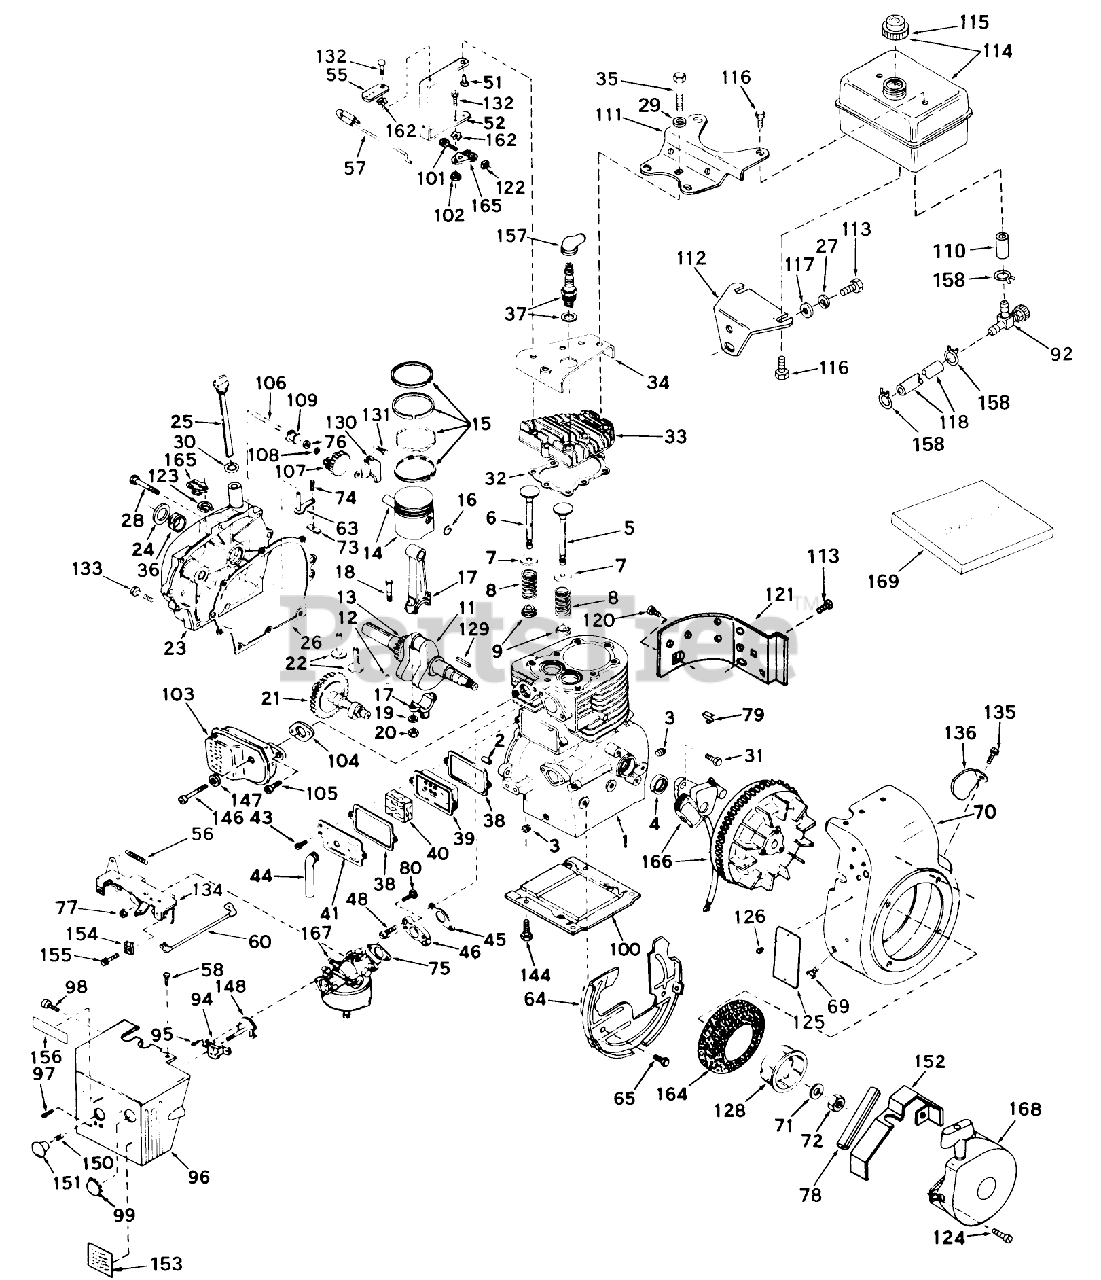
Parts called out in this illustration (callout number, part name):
1	Cylinder Assy. (Incl. Nos. 2, 3 4)
2	Pin-Dowel
3	Plug-Drain, Oil (SQH 1/4-18)
4	Seal, Oil
5	Valve, Intake (Std.)(Incl. No. 9)
5	Valve, Intake (1 /32" oversize)(Incl. No. 9)
6	Valve, Exhaust (Standard)(Incl. No. 9)
6	Valve, Exhaust (1/32" oversize)(Incl. No. 9)
7	Cap-Spring, Valve
8	Spring-Valve
9	Keeper-Spring, Valve
11	Crankshaft Assy. (Incl. Nos. 12 13)
12	Pin, Groove
13	Gear-Crankshaft
14	Piston Pin Assy. (Standard)(Incl. 2 of No. 16)
14	Piston Pin Assy. (.010 oversize)(Incl. 2 of No. 16)
14	Piston Pin Assy. (.020 oversize)(Incl. 2 of No. 16)
15	Ring Set, Piston (Std.)
15	Ring Set, Piston (.010 Oversize)
15	Ring Set, Piston (.020 oversize)
17	Rod Assy., Connecting (Incl. Nos. 18, 19 20)
18	Bolt, Connecting Rod
19	Washer
21	Camshaft, BCR
22	Lifter Valve
23	Cover, Cylinder (Incl. Nos. 24 106)
24	Oil Seal
25	Dipstick, Oil (Incl. No. 30)
26	Gasket-Cover, Cylinder
27	Lockwasher
28	Screw (1/4-20 x 1-1/4)
29	Washer
30	Gasket
31	Screw
32	Gasket-Head, Cylinder
33	CYLINDER HEAD
34	Cover, Cylinder head
35	Screw Hex Hd. Cap
36	Bushing-Crankshaft
37	SPARK PLUG
38	Gasket-Breather
39	Body-Breather
40	Element-Breather
41	Cover-Valve
43	Screw
44	Tube-Breather
45	Gasket-Intake
46	Flange, Carburetor (Incl. Nos. 77 80)
48	Screw
51	Rivet, Split
52	Lever, Governor
56	Spring, Extension
57	Link, Governor to Throttle
58	Screw-Hex Washer Hd.
60	Wire, Ground
63	ROD ASSY, Governor
64	Baffle Blower Housing
65	Screw (1/4-20x19/32)
69	Screw, Hex Hd.
70	Housing, Blower
71	Washer
73	Yoke-Governor
74	Screw (6-40x5/16)
75	Gasket-Carburetor
76	Washer-Flat
77	Nut and Lock Washer (1/4-28)
78	Seal, Snowguard
79	51004 GIL ROTARY TI
80	Screw
92	Valve-Shut Off
94	Bracket-Choke
95	Screw (10-32 x 1/2)
96	Cover, Carburetor
97	Screw (8-32 X 5/16)
98	Screw, Pan Hd. Metal
99	Plug
100	Base Engine
101	Screw
102	Nut-Lock
103	Muffler
104	Gasket Exhaust
105	Screw
106	Shaft-Governor
107	Governor Gear ASM
108	Ring-Retaining
109	Spool-Governor
110	Line-Fuel (8.62)
111	Bracket, Fuel Tank-Upper
112	Bracket, Fuel Tank-Lower
113	Screw (1/4-20x19/32)
114	53023/VAR.10/16HP O
115	Cap, Fuel
116	Screw (1/4-15x7/8)
117	Washer
118	Line-Fuel
120	Screw
121	Emnsion, Blower Housing
122	Nut-Lock
123	Ring-Retaining
124	Screw
125	IDENTIFICATION PLATE
126	DRIVE STUD
128	Cup-Starter
129	Key, Flywheel
130	Bracket, Governor
131	Screw (10-32 x 35/64)
132	Screw
133	Screw
134	Bracket Assy., Speed Control (Incl. No. 56)
135	Screw, Pan Hd. Metal
136	Screw
144	Screw
146	Screw Hex Hd. Cap
147	Washer
148	Plate, Choke
150	Spring, Compression
151	Knob, Choke
152	Guard, Starter
153	Decal, Operating
154	Conduit
155	Screw (10-32 x 3/8)
156	Decal, Choke
157	Cover-Spark Plug
158	Clamp-Line, Fuel
162	Washer-Lock
164	Screen, Air
165	Clamp-Lever, Governor
166	Magneto
167	Carburetor
168	Starter Assy., Rewind
169	Gasket Set (Incl. Items Marked *)
